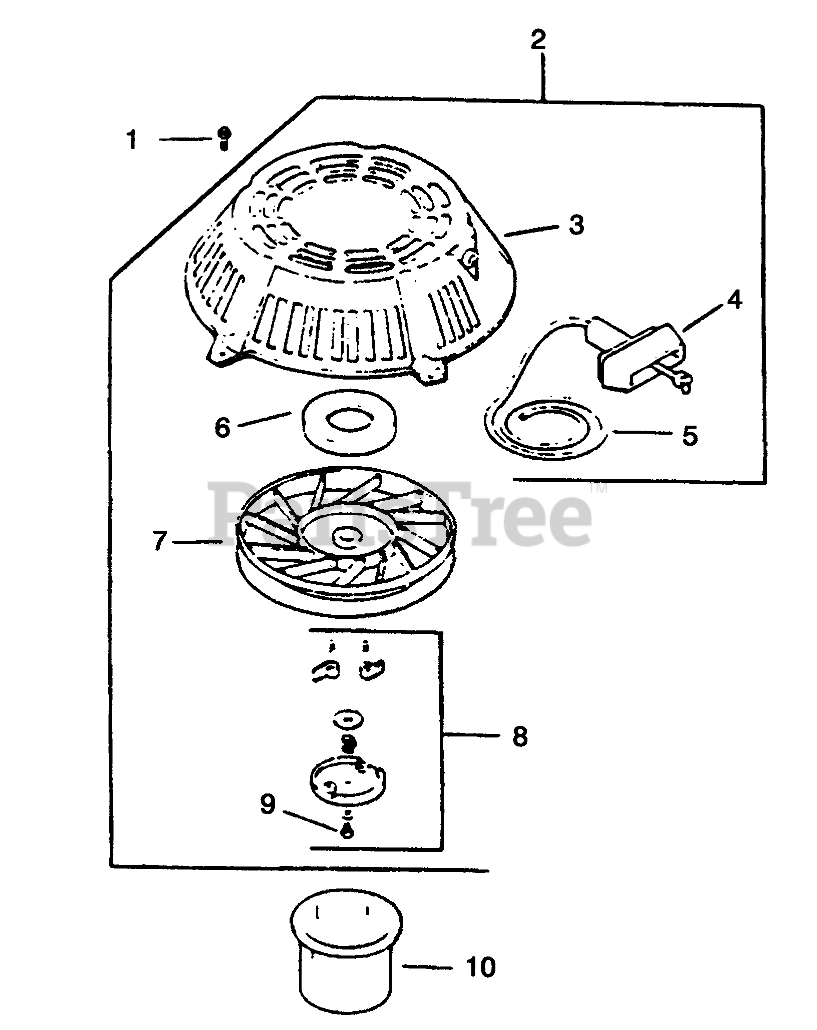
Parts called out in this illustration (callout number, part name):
1	Screw
2	Starter (Incl.Ref. #3-9)
3	Housing-Starter
4	Handle
5	Rope-Starter
6	Spring & Keeper
8	Kit-Dog Replacement (Incl Ref. #9)
9	Screw-Pozidrive
10	Cup-Driver
